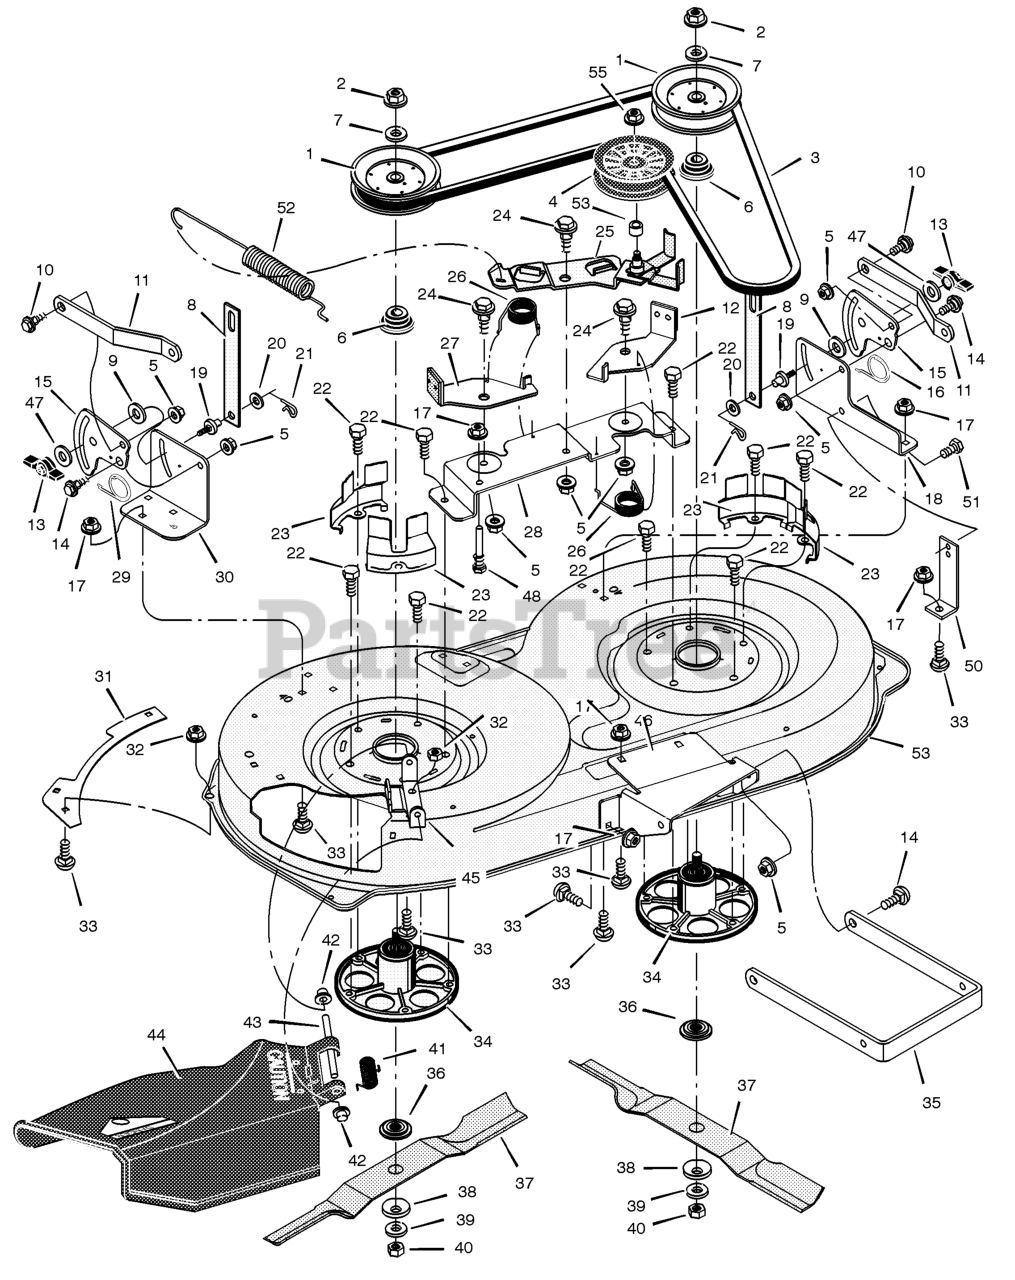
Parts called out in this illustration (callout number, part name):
1	Pulley, Jackshaft
2	Nut, Hex
3	Belt, Mower Drive
4	Pulley, Idler
5	Nut, Flange
6	Spacer, Pulley
7	Washer
8	Link, Lift
9	Pad, Friction
10	Bolt, Shoulder
11	Bracket, Suspension
12	Pad Assembly, Left Brake
13	Knob
14	Bolt, Shoulder
15	Plate, Suspension
17	Nut, Flange
18	Bracket, Suspension
19	Pin, Hanger
21	Pin, Cotter
22	Bolt
23	Cover, Pulley
24	Bolt, Shoulder
25	Arm, Idler
27	Pad Assembly, Right Brake
28	Bracket Assembly, Brake
30	Bracket, Suspension
31	Plate
32	Nut, Flange
33	Bolt, Carriage
34	Mandrell
35	Bracket, Suspension
36	Adapter, Blade
42	Cap, Push On
43	ROD, Deflector
44	Deflector Assembly
45	Bracket, Deflector
46	Bracket, Front Hanger
48	Guide, Belt
50	Bracket, Support
52	Spring, Extension
54	Housing, Blade
55	Nut, Flange
